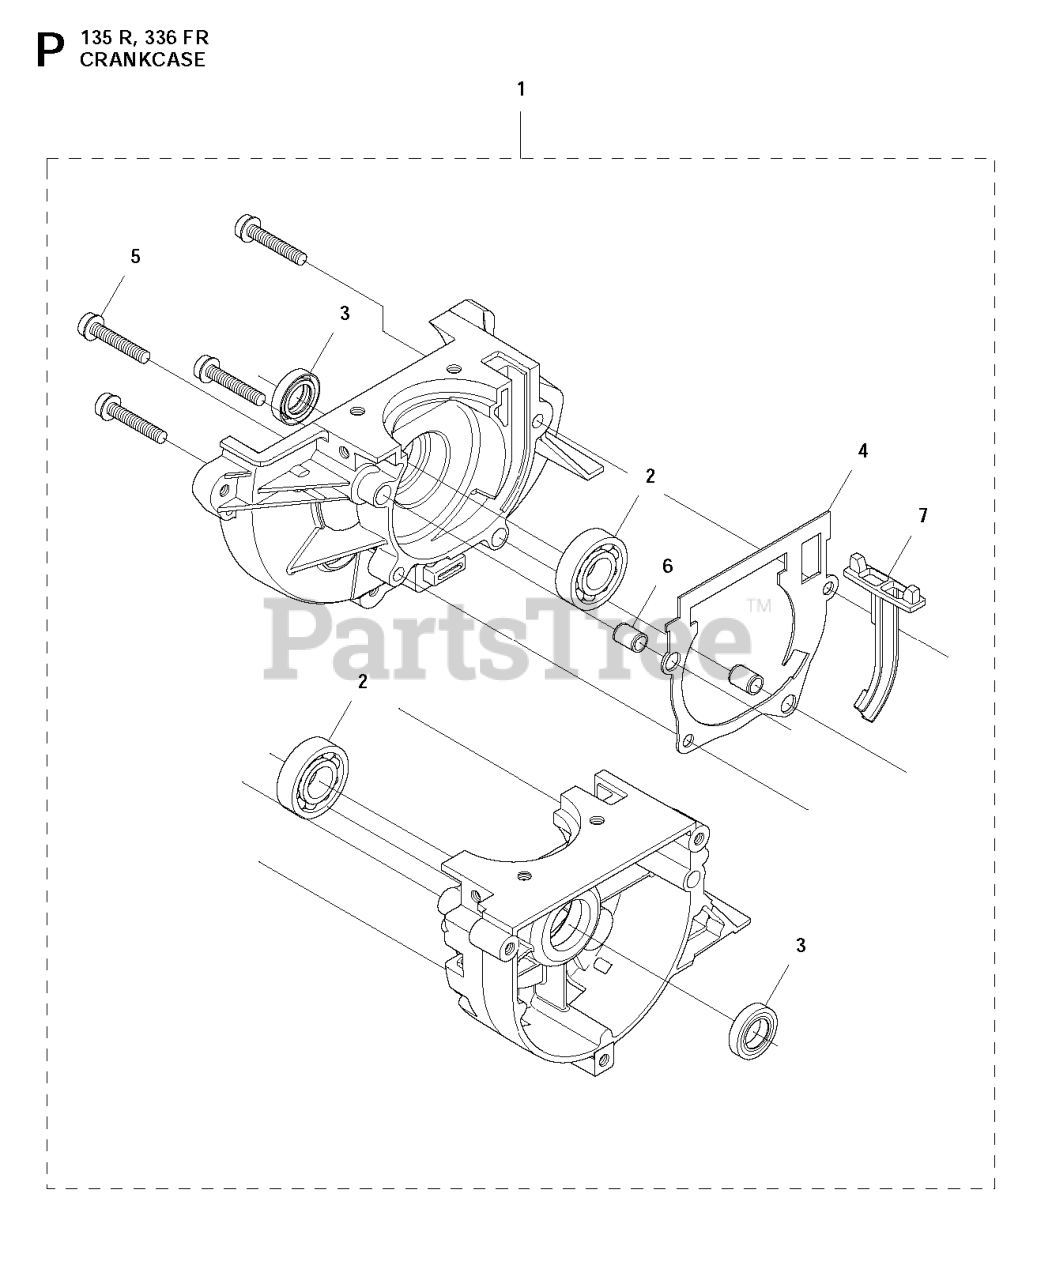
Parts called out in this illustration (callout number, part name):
1	CRANKCASE ASSY
2	BALL BEARING
3	SEALING RING
4	GASKET CRANKCASE
6	GUIDE BUSHING
7	INSERT, CARTER
